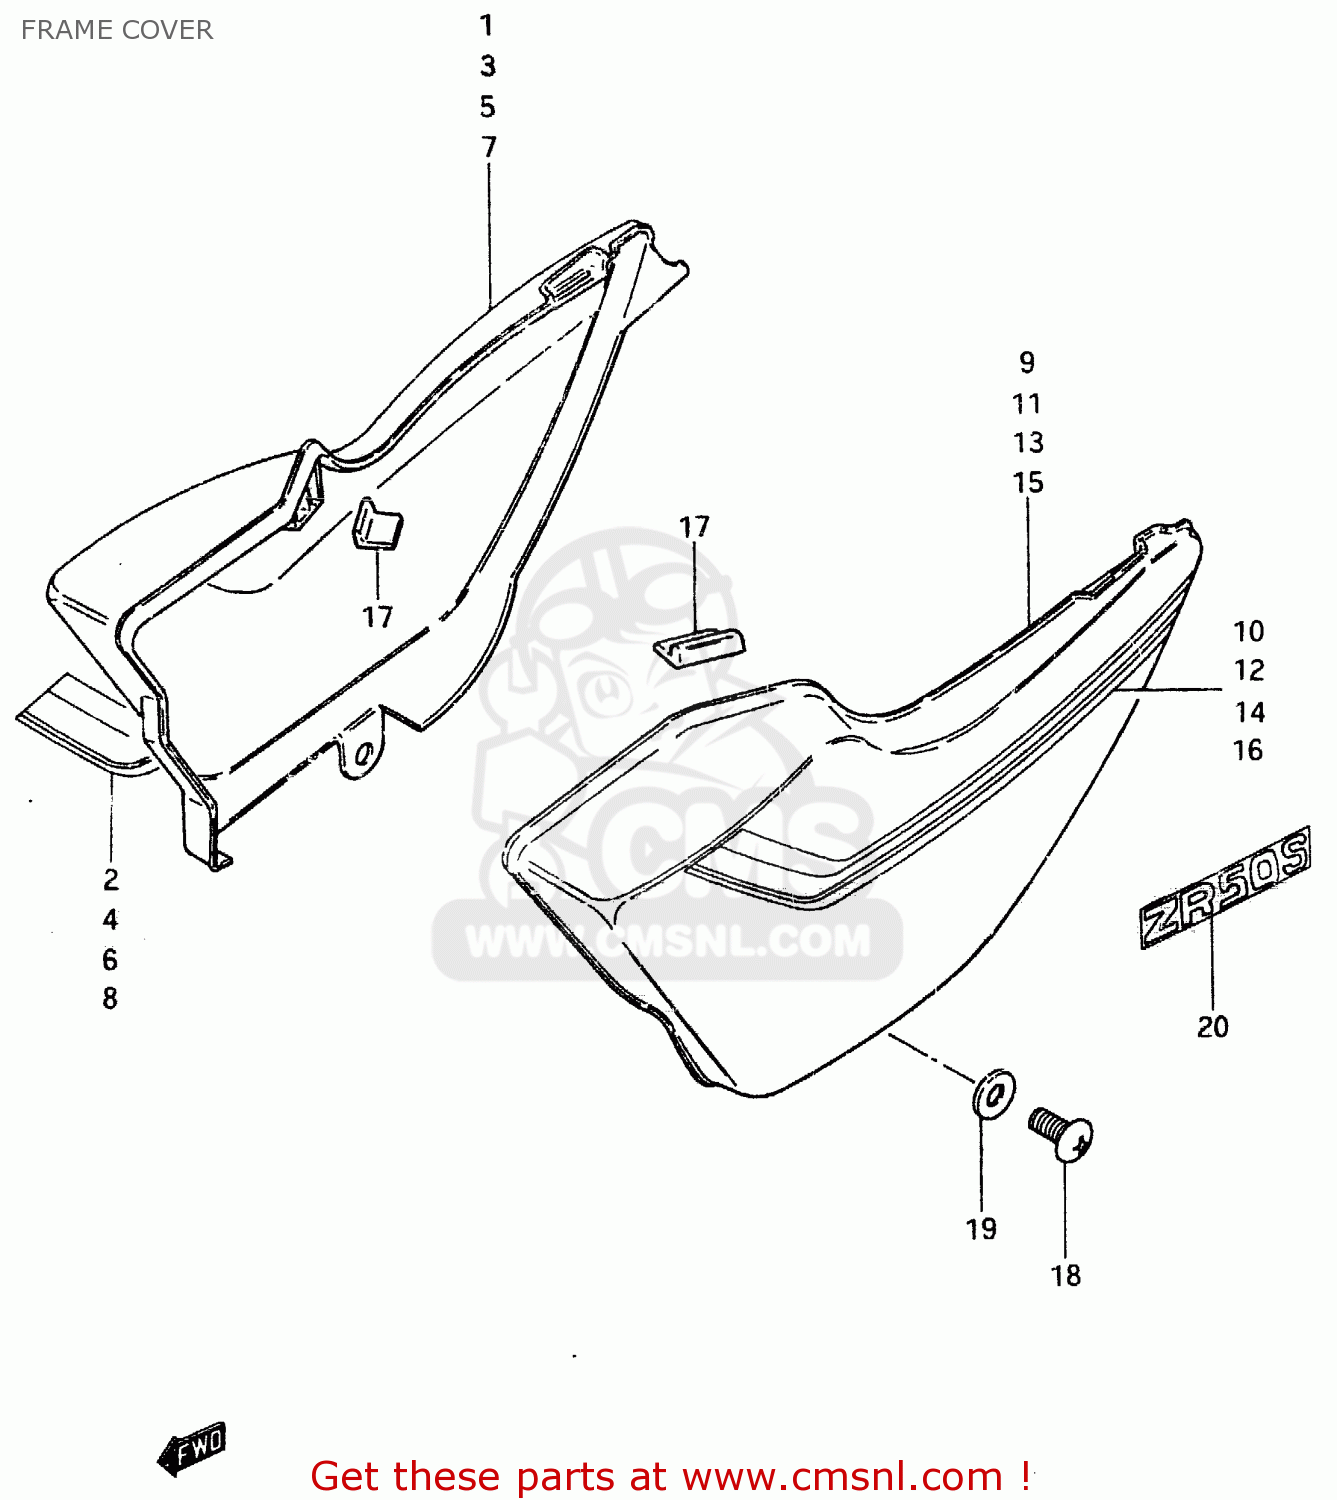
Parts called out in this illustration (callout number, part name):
1	COVER, FRAME RH
2	TAPE, RH
3	COVER, FRAME RH
4	TAPE, RH
5	COVER, FRAME RH
6	TAPE, RH
7	COVER, FRAME RH
8	TAPE, RH
9	COVER, FRAME LH
10	TAPE, LH
11	COVER, FRAME LH
12	TAPE, LH
13	COVER, FRAME LH
14	TAPE, LH
15	COVER, FRAME LH
16	TAPE, LH
17	CUSHION,FRAME COVER
18	SCREW
19	WASHER
20	EMBLEM
